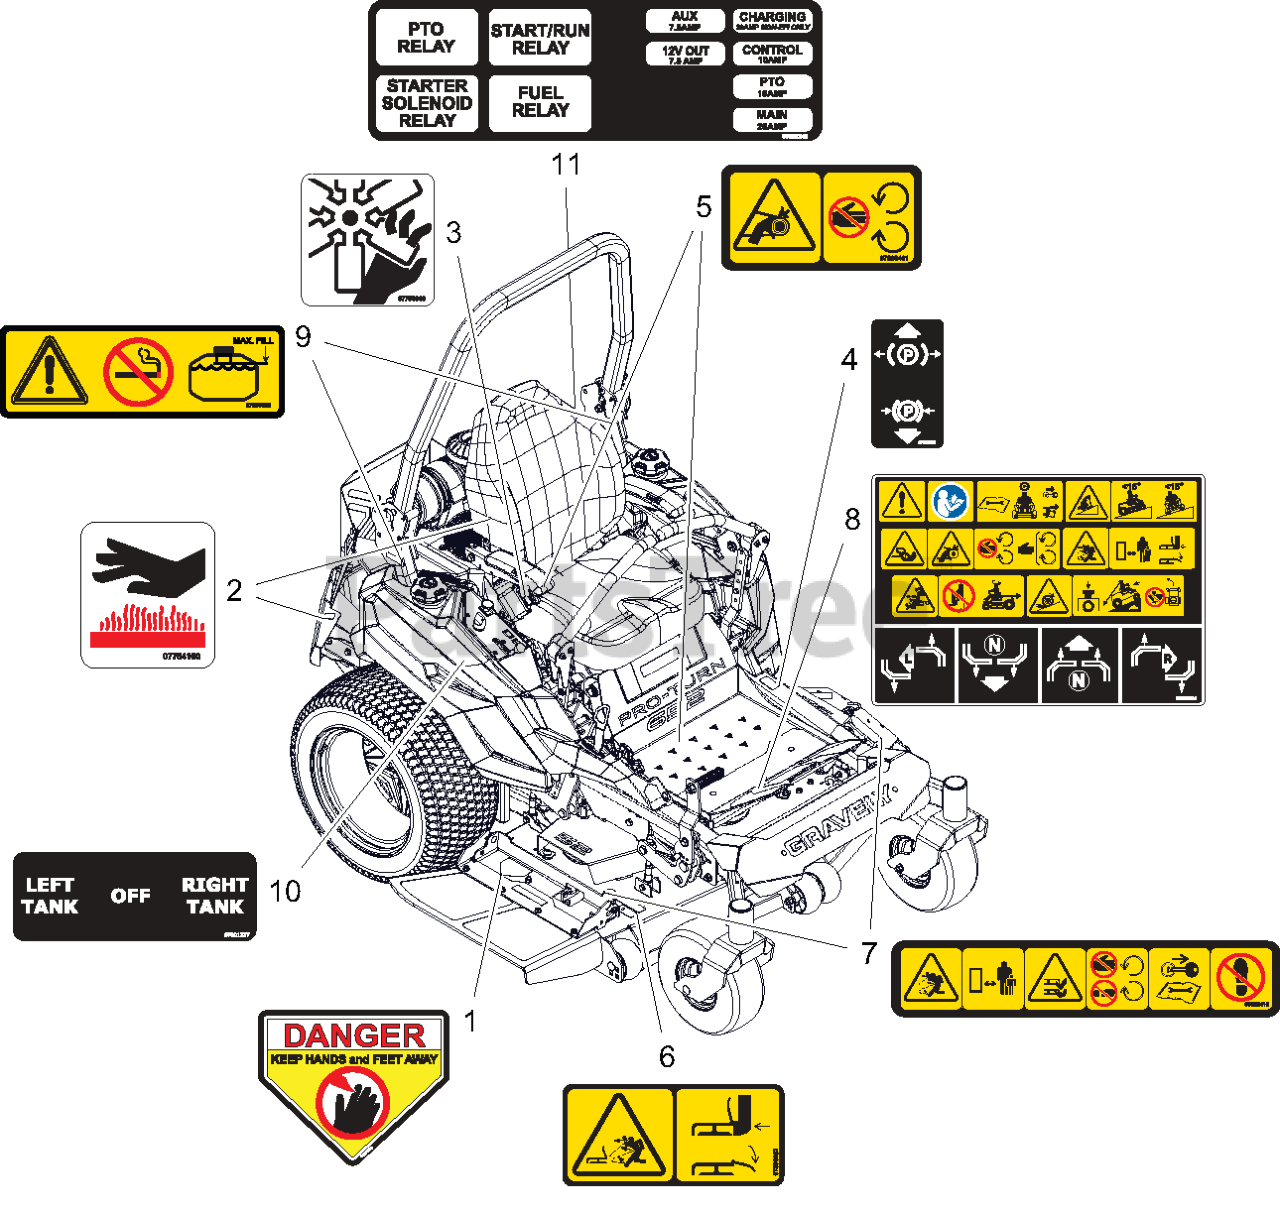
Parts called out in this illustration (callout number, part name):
1	DECAL, DANGER
2	DECAL, HOT SURFACE
3	DECAL, DANGER FAN
4	DECAL, PARKING BRAKE LEVER
5	DECAL, SAFETY - GUARDING
6	DECAL, SAFETY - DECK GUARDING
7	DECAL, DECK SAFETY
8	DECAL, INSTR SAFETY
9	DECAL, FUEL WARNING
10	DECAL, FUEL VALVE
11	DECAL- FUSE BOX - PT600
